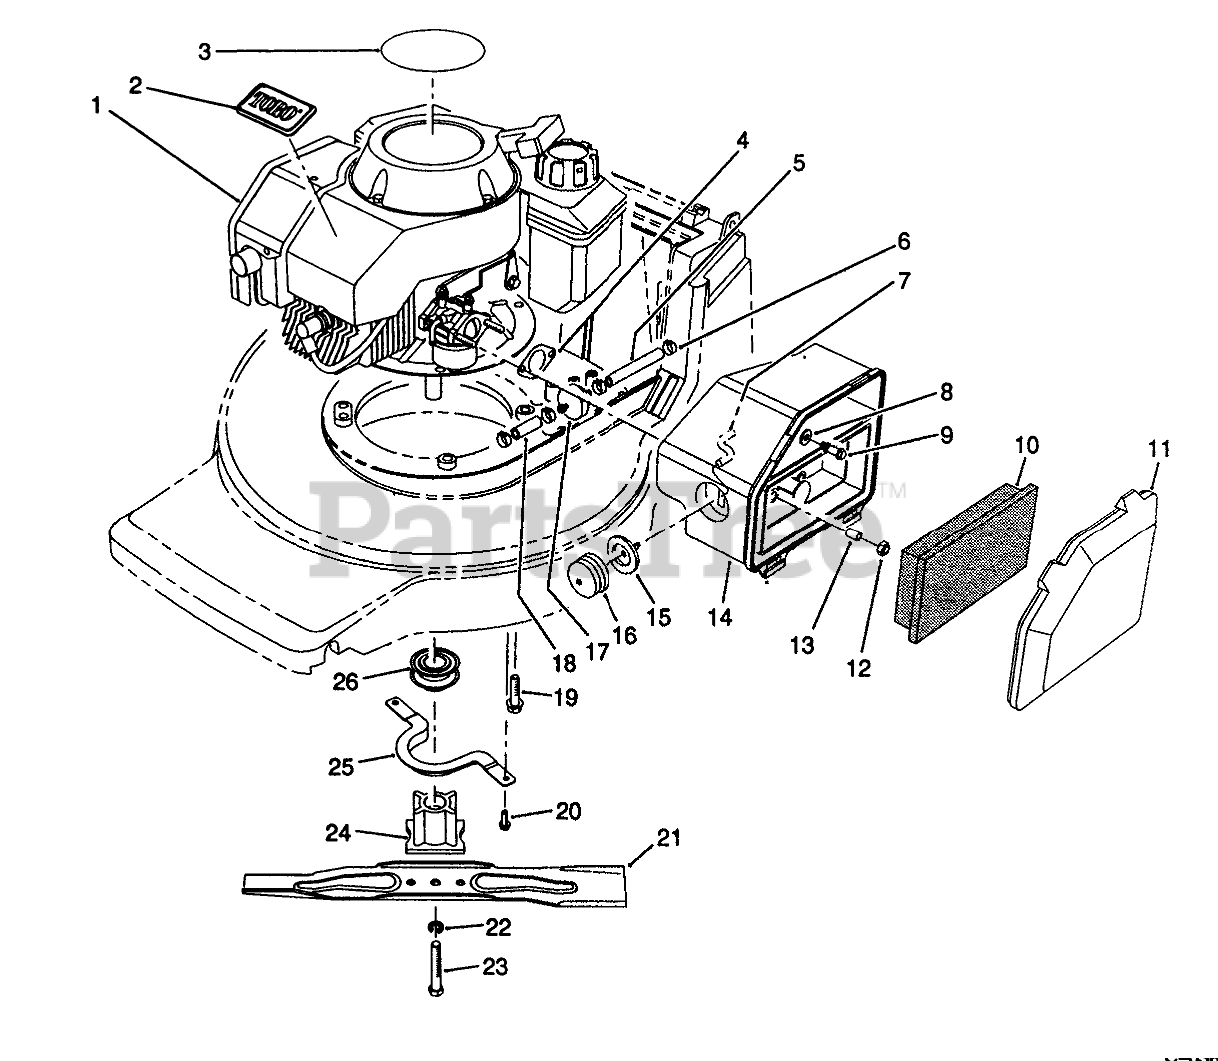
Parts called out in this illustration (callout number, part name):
1	Engine-2 Cycle
2	TORO LOGO PLT
3	DECAL- 2 CYC RECOIL
4	GASKET-AIR CLEANER
5	HOSE-FUEL
6	CLAMP-FUEL LINE
7	HOSE-PRIMER
8	WASHER-FLAT
9	SCREW-HH
10	ELEMENT-AIR CLEANER
11	COVER-AIR CLEANER
13	SPACER
14	BODY-AIR CLEANER
15	BODY-PRIMER
16	BULB-PRIMER
17	FILTER-FUEL
18	HOSE-FUEL
19	SCREW-HHF, WHIZ
20	SCREW-HWH
21	Blade-48cm
22	WASHER-LOCK
23	BOLT-BLADE
24	BLADE RETAINER - 25 MM
25	Guide-Belt
26	PULLEY-DRIVE, ZONE START
